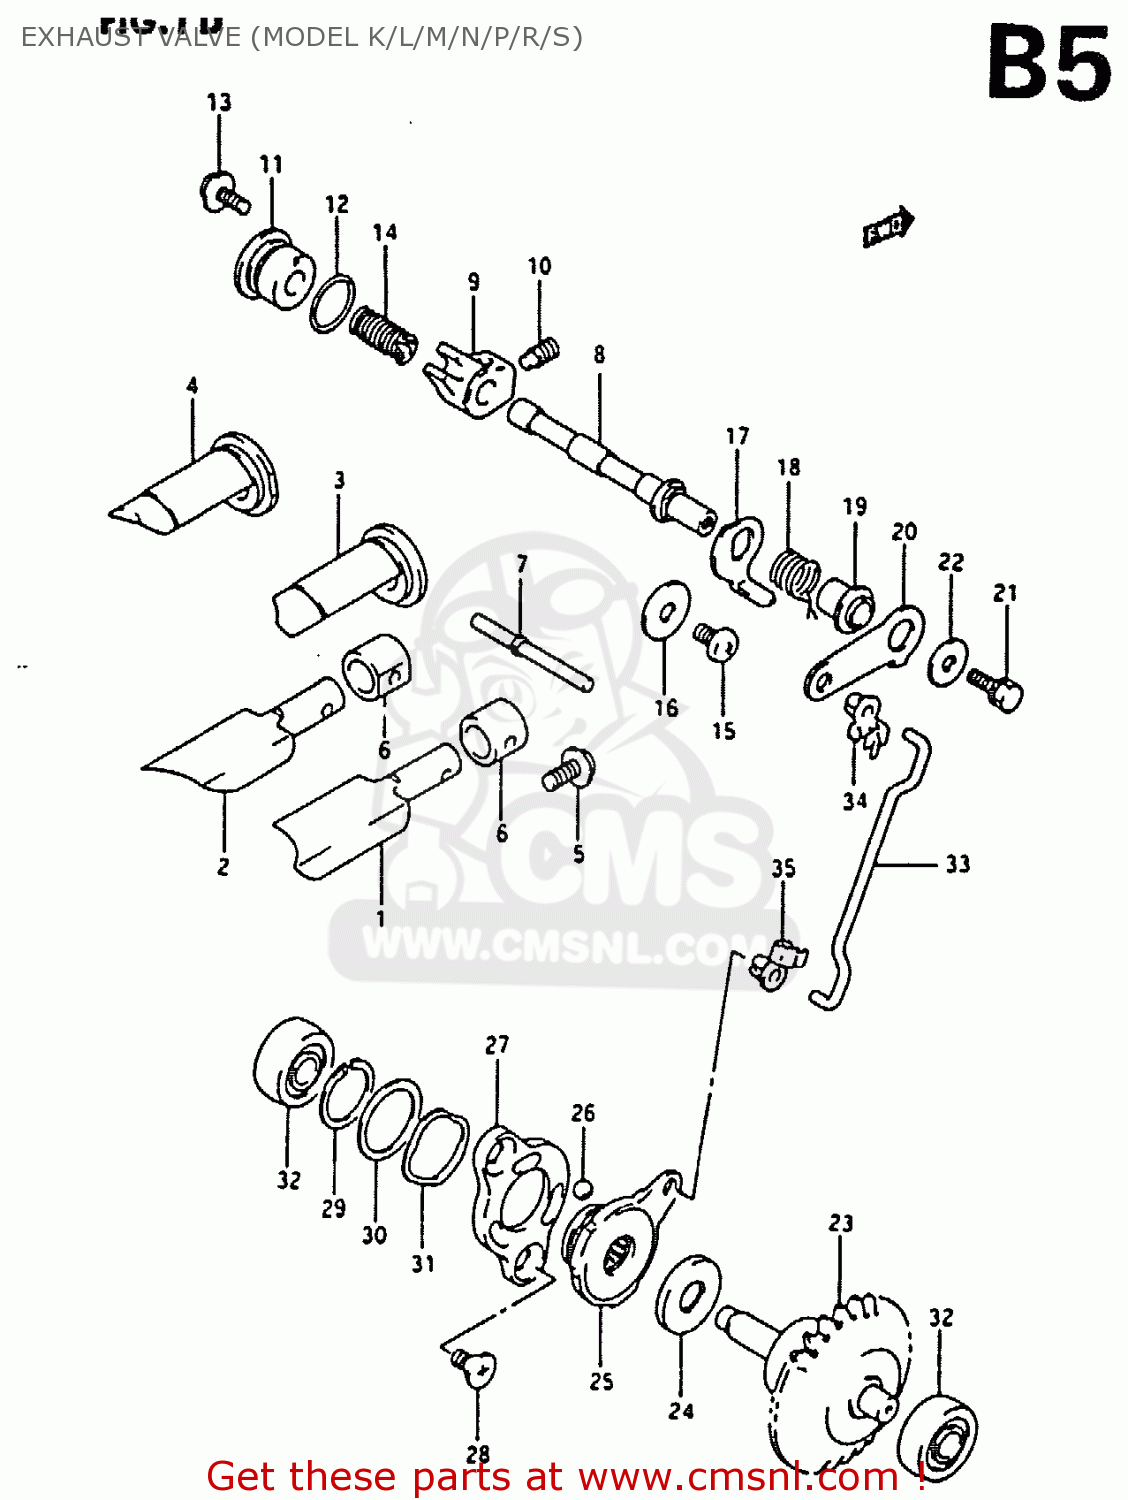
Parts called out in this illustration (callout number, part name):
1	VALVE,EXHAUST,R
2	VALVE,EXHAUST,L
3	GUIDE,EXHAUST VALVE,R
4	GUIDE,EXHAUST VALVE,L
5	SCREW
6	SPACER,EXHAUST VALVE
7	PIN,EXHAUST VALVE 48.5MM
8	SHAFT,EXHAUST VALVE
9	ARM,EXHAUST VALVE SHAFT
10	SCREW(6X10)
11	CAP,EXHAUST VALVE
12	O-RING
13	BOLT
14	SPRING
15	SCREW
16	WASHER
17	LEVER,EXHAUST VALVE NO
18	SPRING
19	SPACER,EXHAUST VALVE
20	LEVER,EXHAUST VALVE NO.1
21	BOLT
22	WASHER (5.5X16X1.2)
23	GOVERNOR ASSEMBLY,EXHAUST
24	BEARING(10X22X2.8)
25	ACTUATOR,EXHAUST VALVE
26	BALL
27	STARTER,EXHAUST VALVE ACTUATOR
28	SCREW(5X10)
29	CIRCLIP
30	SHIM(19.1X25X0.3)
31	WASHER
32	BEARING(8X22X7)
33	ROD,EXHAUST VALVE
34	BUSH,EXHAUST VALVE ROD NO.1
35	BUSH,EXHAUST VALVE ROD NO.2
